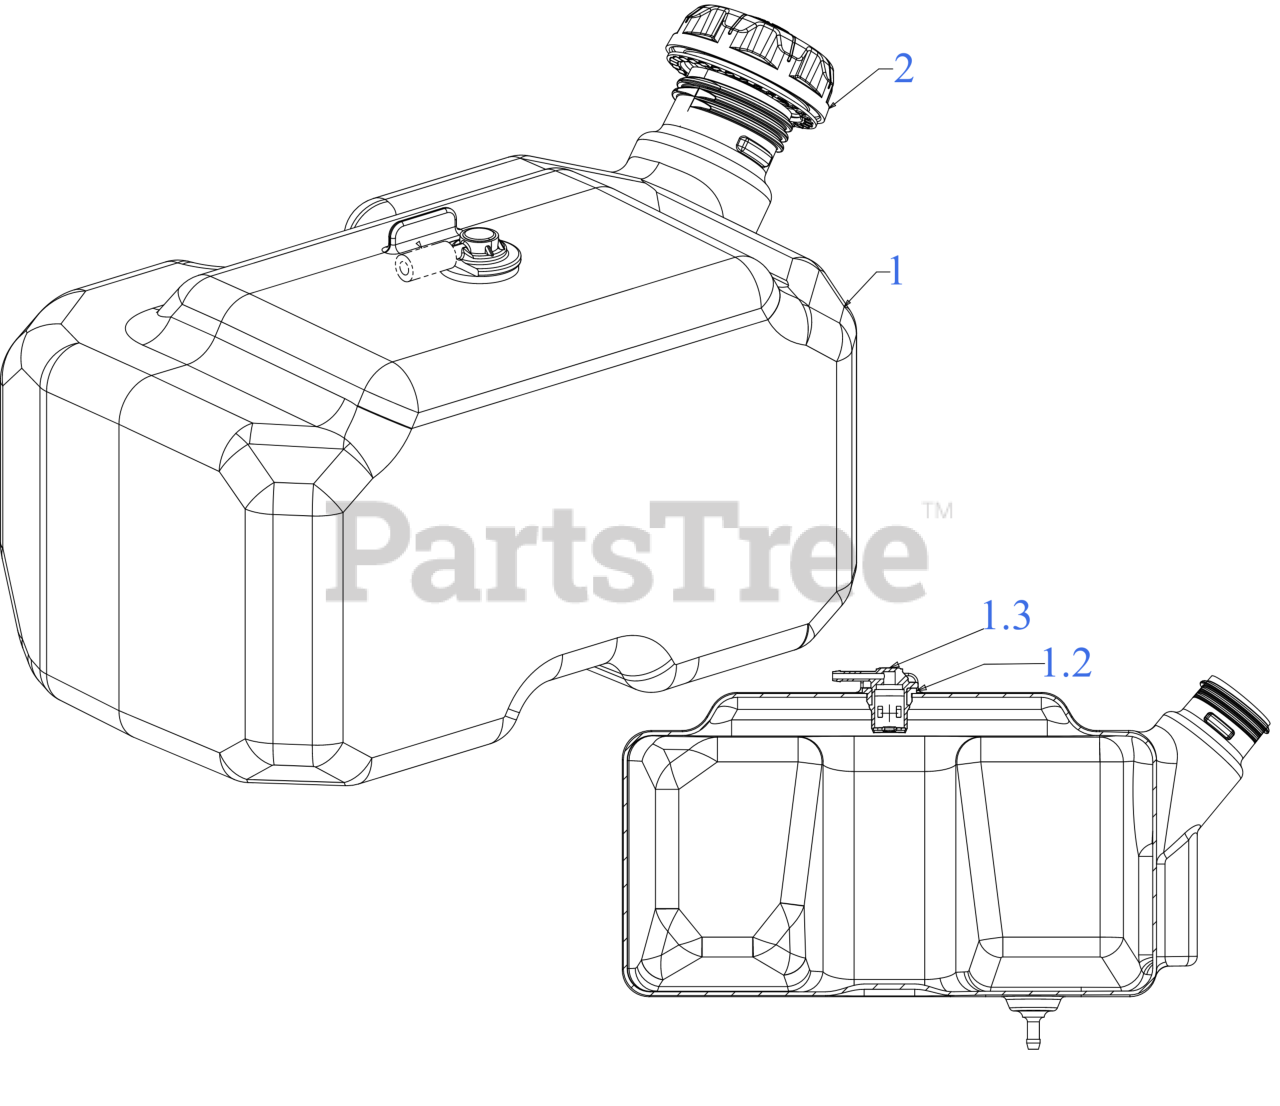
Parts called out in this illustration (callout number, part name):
1	FUEL TANK ASSEMBLY
1.2	RUBBER GROMMET 23.0 ID x 35.5 OD
1.3	ROLLOVER FUEL VALVE
2	FUEL CAP W/TETHER VENTED
